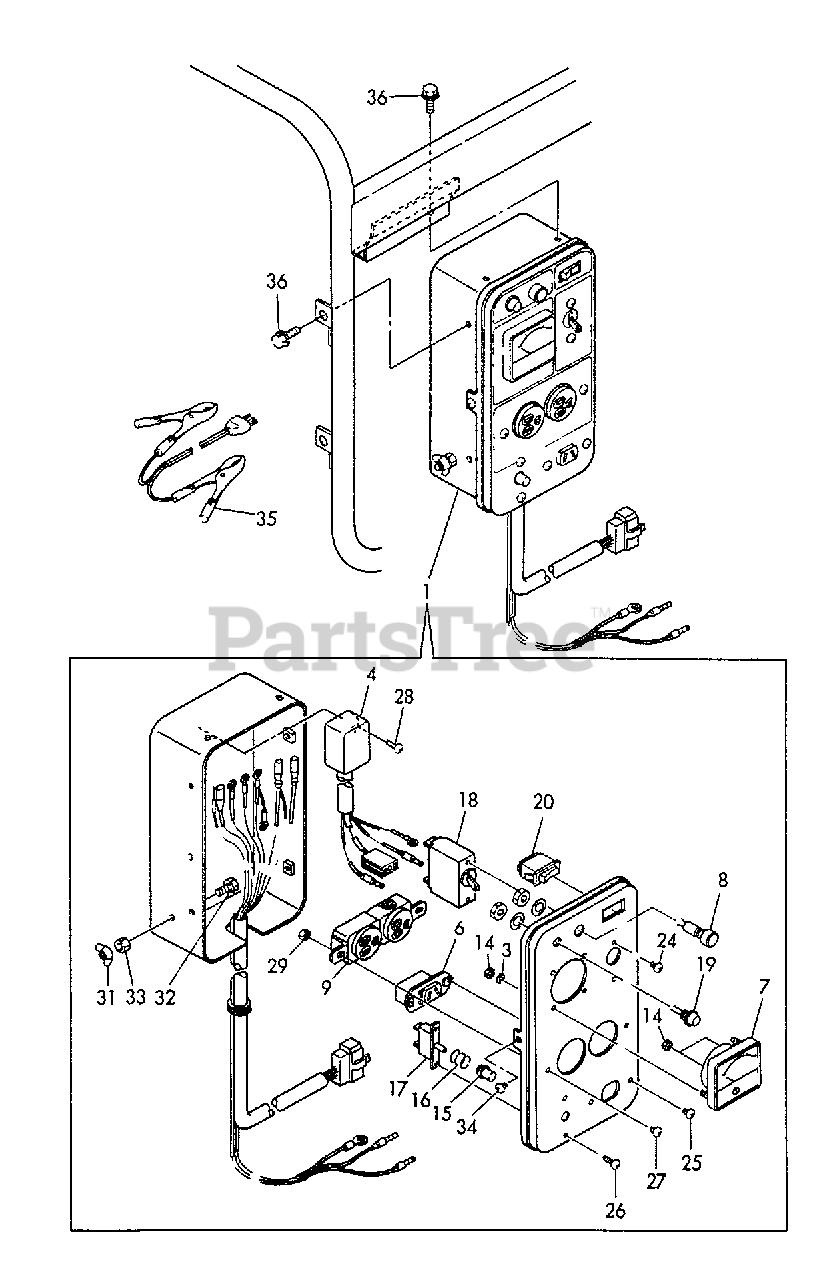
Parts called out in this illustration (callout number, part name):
1	PANEL BOX ASSY
3	WASHER, DECOMP.
4	SENSOR UNIT, OIL
6	DC CONNECT
7	VOLTAGE METER (150V)
8	LAMP, PILOT
9	AC CONNECT
14	NUT - 3
15	CAP, BREAKER
16	SPRING BREAKER
17	BREAKER
18	AC BREAKER
19	LAMP, OIL ALERT
20	SWITCH
24	SCREW - 3×6
25	SCREW - 3×6
26	SCREW 3×12
27	SCREW - 4×6
28	SCREW - 5×10
29	NUT - 4
31	WINGNUT - 6
32	BOLT - 6×16 -- PLATED
33	LOCKNUT - 6 -- PLATED
34	SCREW - 4×6
35	CABLE, CHARGING
36	BOLT - 6×8 -- PLATED
